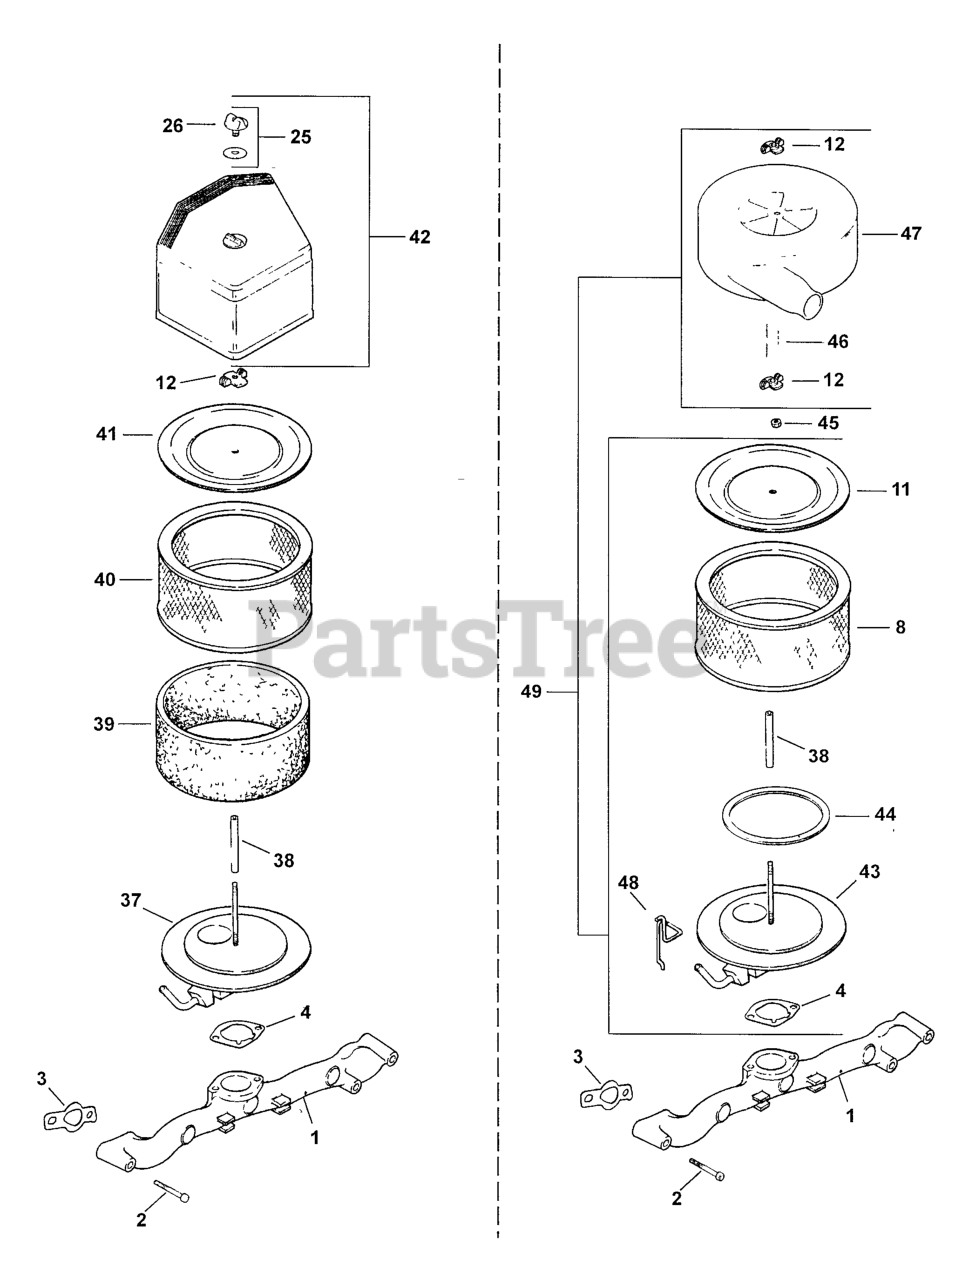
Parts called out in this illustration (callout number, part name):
1	MANIFOLD, INTAKE
2	Screw, hex. flange M6x1.0x55
3	GASKET, INTAKE MANIFOLD USE 24 041 79-S
4	GASKET, AIR CLEANER BASE
8	ELEMENT, AIR CLEANER - Also available Retail Packaged 47 883 03-S1 Air Filter Kit
11	COVER, INNER AIR CLEANER
12	NUT, WING
43	ELBOW, AIR CLEANER - (#24 054 32-S)
44	KIT - USE 24 743 18
45	NUT - USE M-641060
47	COVER - USE 24 096 53
48	LINKAGE, CHOKE
49	KIT, PLENUM AIR CLEANER
